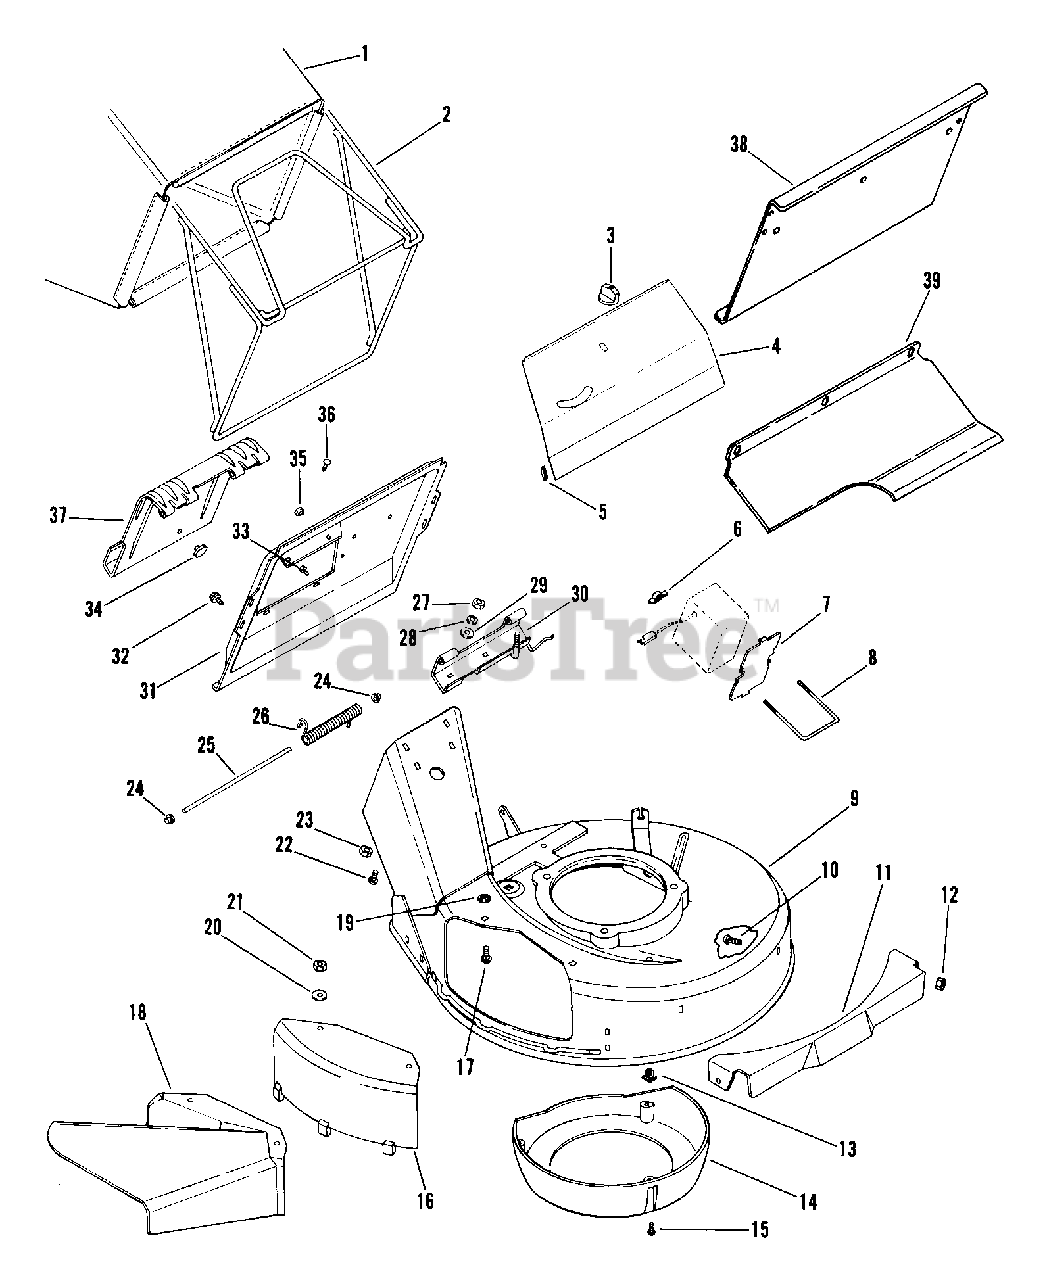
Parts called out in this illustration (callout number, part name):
1	BAG,CONSUMER BLACK 15 OZ/YD2
1	BAG,COMMERCIAL WHITE
2	BAGGER FRAME
3	WING - NUT
4	DRIVE COVER
5	TRIM BUMPER
6	NUT-WING 8-32
7	HOLD DOWN PLATE
8	U-BOLT
9	MOWER PAN W/DECALS
9	MOWER PAN W/DECALS MULCHER
10	BLT-RDHDSQSHNK .31-18X.50 YZ
11	FRONT PANEL
12	NUT-LK .312-18 GR A PL
13	PLASTIC GROMMET
14	CENTER BAFFLE
15	SCR-TAP 10-16X.62 SLPH PL AB
16	SIDE DISCHARGE COVER
17	BLT-RDHDSQNK .31-18X.75 SHT PL
18	DISCHARGE CHUTE
19	NUT-PUSH .312
20	WSHR-FL-STL .38X.875X.083 PL
21	NUT-LK-NYL.312-18 PL
22	BLT-RDHDSQNK .25-20X.62 PL
23	NUT-LK-FLG .250-20 PL
24	PUSH NUT, .25
25	DOOR PIN
26	SG-TORS .120X.68X3.09
27	NUT-HEX .250-20 PL
28	WSHR-LK .250X.077 HVY PL
29	WSHR-FL-STL .380X.875X.179 PL
30	HINGE BASE
30	HINGE BASE WELDMENT
31	CATCHER PLATE
32	SCR-TAP 12-24X.50 HWH PL TR
33	SCR-TAP 10-24X.375 TORX PHD
34	BUTTON BUMPER
36	@BLT-RHDSSQNK .25-20X.38 G2YZ
37	CATCHER PLATE DOOR
38	GUARD PLATE
39	DEFLECTOR BRACE
